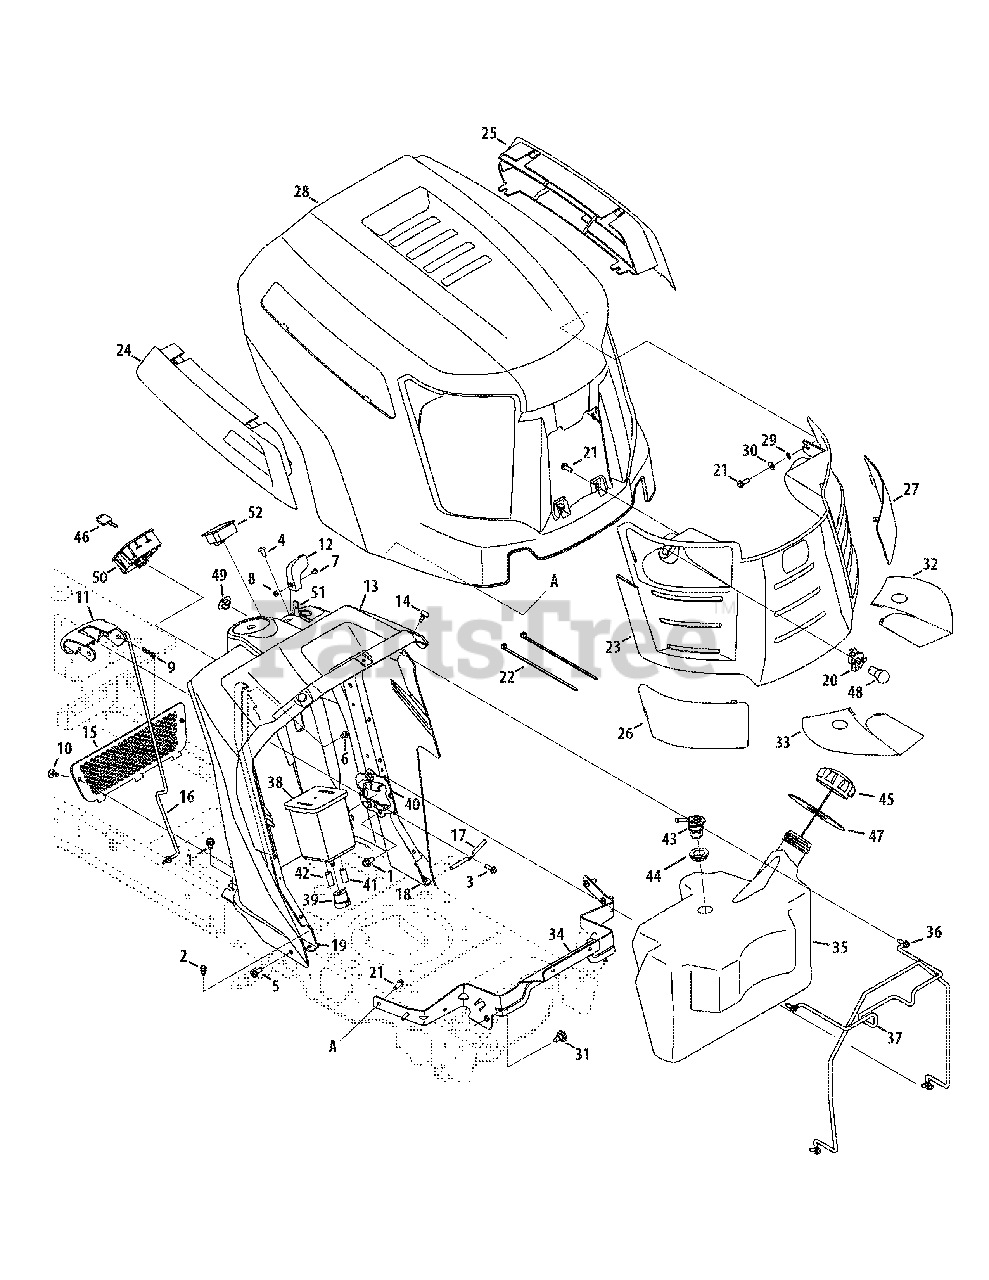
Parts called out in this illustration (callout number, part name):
1	Screw, Self-tapping, 5/16-18, .750
2	Screw, Self-tapping, 1/4-20, 0.500
3	Screw, HL, 1/4-15, 0.750
4	Screw, Ab, 1/4-14, 0.625,
5	Screw, Self-tapping, 5/16-18, 0.750
6	Screw, Self-tapping, 1/4-20 x .625
7	Screw, Mach, #8-32, 0.375
8	Nut, Hex, #8-32
9	Pin, Cotter, Bow-Tie 72
10	Clip, Ratchet, .250 Dia
11	Lever, Dash, Cruise/Brake
12	Knob, Throttle
13	Dash Panel, Man PTO
14	Bumper, .62 Dia X .3
16	Rod, Control, Latch Cub
17	Rod, Lever, Bent
18	Support, Dash, Plate LH
19	Support, Dash, Plate RH
20	Socket, Lamp
21	Hex Washer BosScrew™, 1/4 Dia. x .750
22	Tie, Cable, Push Mount 7.5 Lg
23	Grille Asm
24	Scoop, Hood, RH
25	Scoop, Hood, LH
26	Lens, Hood, RH
27	Lens, Hood, LH
28	Hood
29	Washer, Lock, 1/4, External
30	Washer, Flat, .271, .630, .065
31	Screw, Shoulder, .43x.29, 5/16-18
32	Reflector, LH
33	Reflector, RH
34	Bracket, Pivot, Hood
35	Tank, Fuel, 3.75 Gal.
35	Tank, Fuel, 3.30 Gal.
36	Screw, Self-tapping, 1/4-20, .625
36	Screw, Self-tapping, 1/4-20, .75
37	Rod, Support, Fuel Tank
38	Cnstr, Carbon, 5 Gallon
39	Filter, Vent, Canister
40	Bracket, Adapter, Canister
41	Hose, Fuel, Low Perm, 3/16 White
42	Hose, Fuel, Low Perm, 7/32 Yelllow
43	Valve, Rollover Grommet
44	Grommet, Rubber, 23.0 ID
45	Cap, Fuel
46	Key, Ignition
47	Gasket, Fuel Tank
48	Lamp, 12v
49	Plug, Choke
50	Module Switch, Ignition
51	Cable, Throttle/Choke, 28"
52	Meter, Indicator
